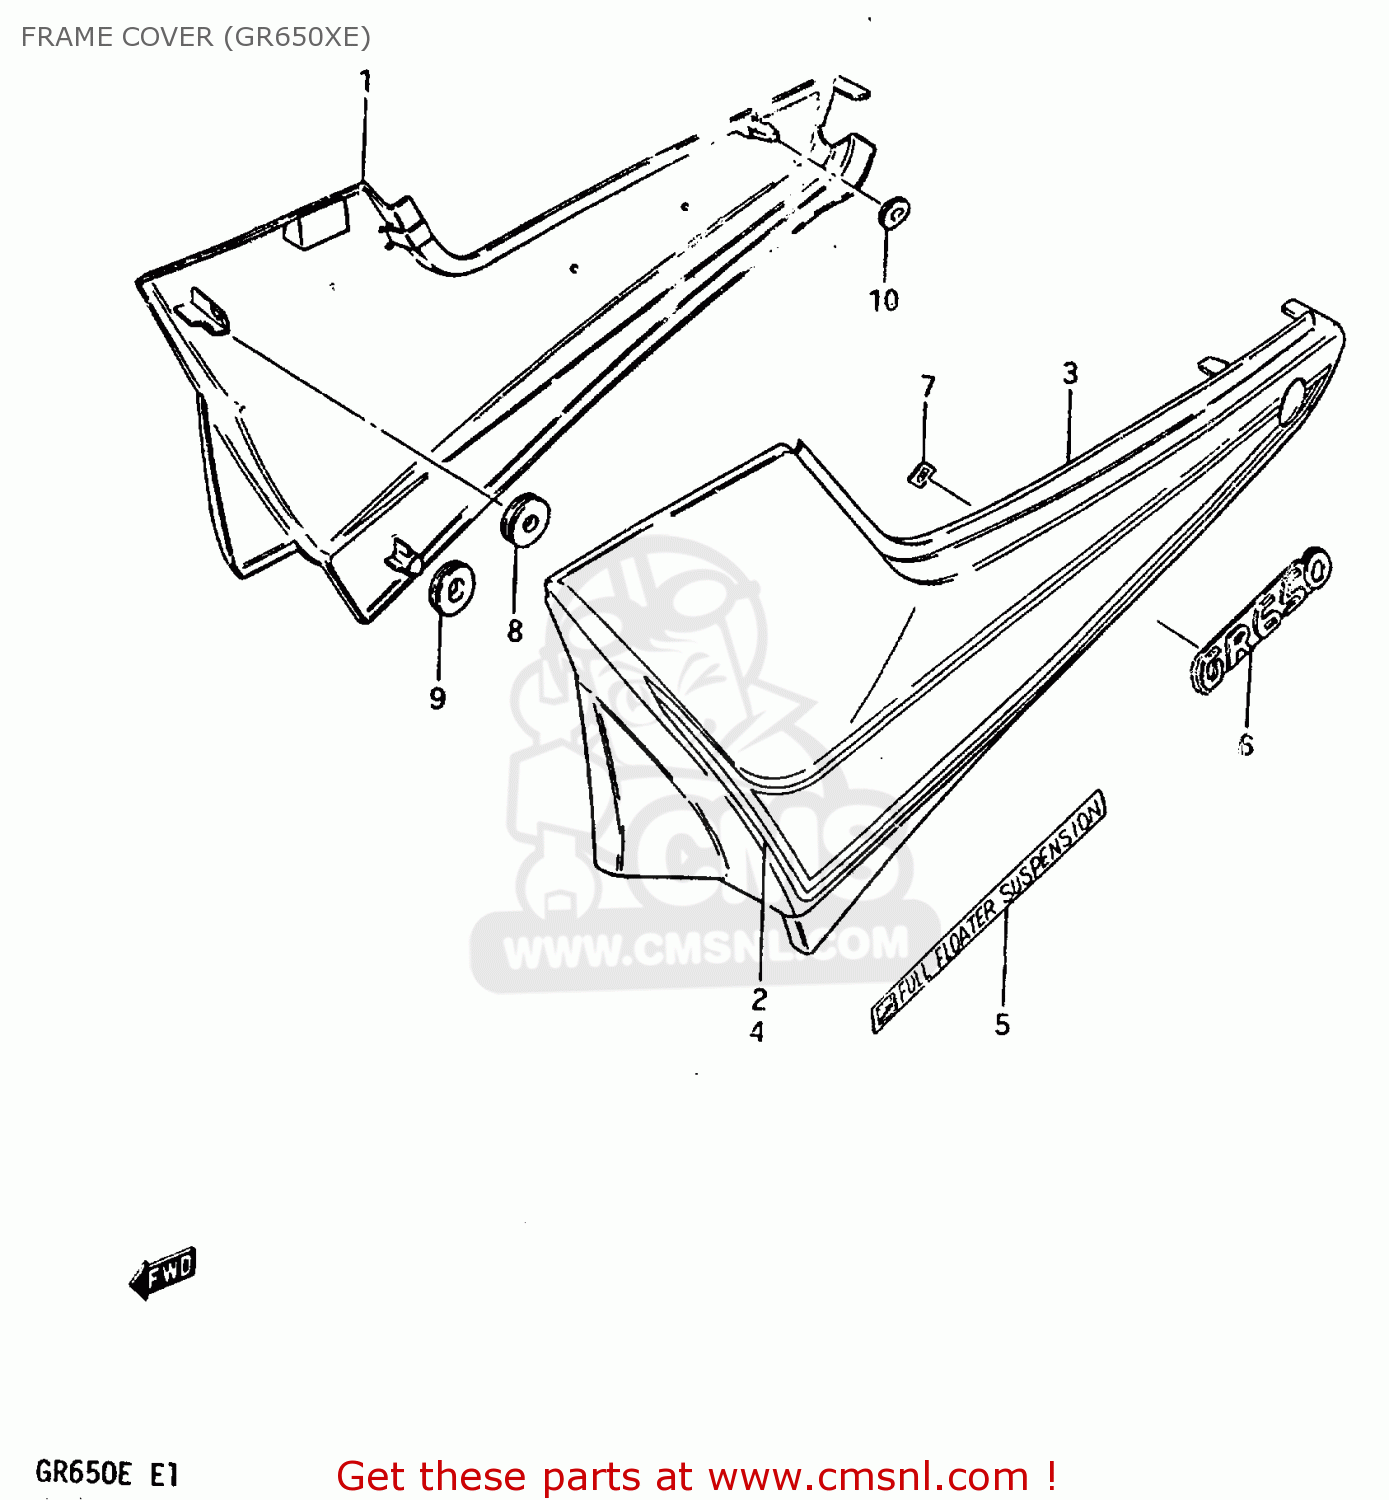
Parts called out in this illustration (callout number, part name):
1	COVER, FRAME RH (RED)
2	TAPE, RH
3	COVER, FRAME LH (RED)
4	TAPE, LH
5	EMBLEM
6	EMBLEM,FRAME COVER
7	NUT
8	CUSHION
9	CUSHION
10	CUSHION
